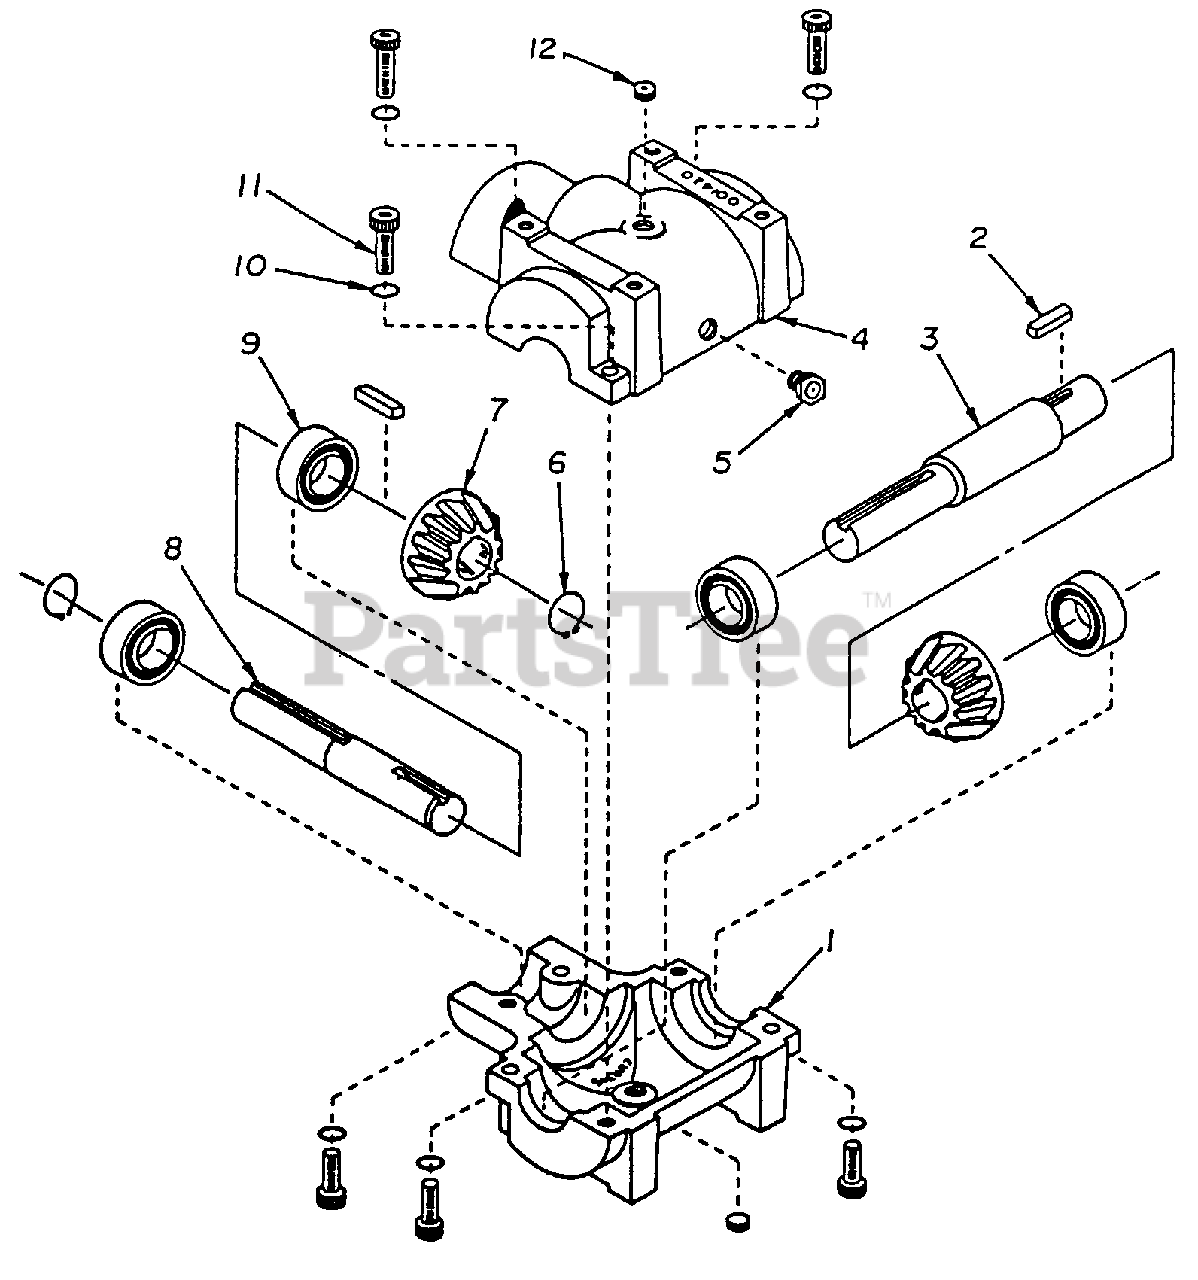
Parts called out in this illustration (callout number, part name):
2	KEY
6	RETAINING RING
9	BALL BEARING
10	LOCKWASHER
11	ALLEN HEAD BOLT
12	PIPE PLUG
